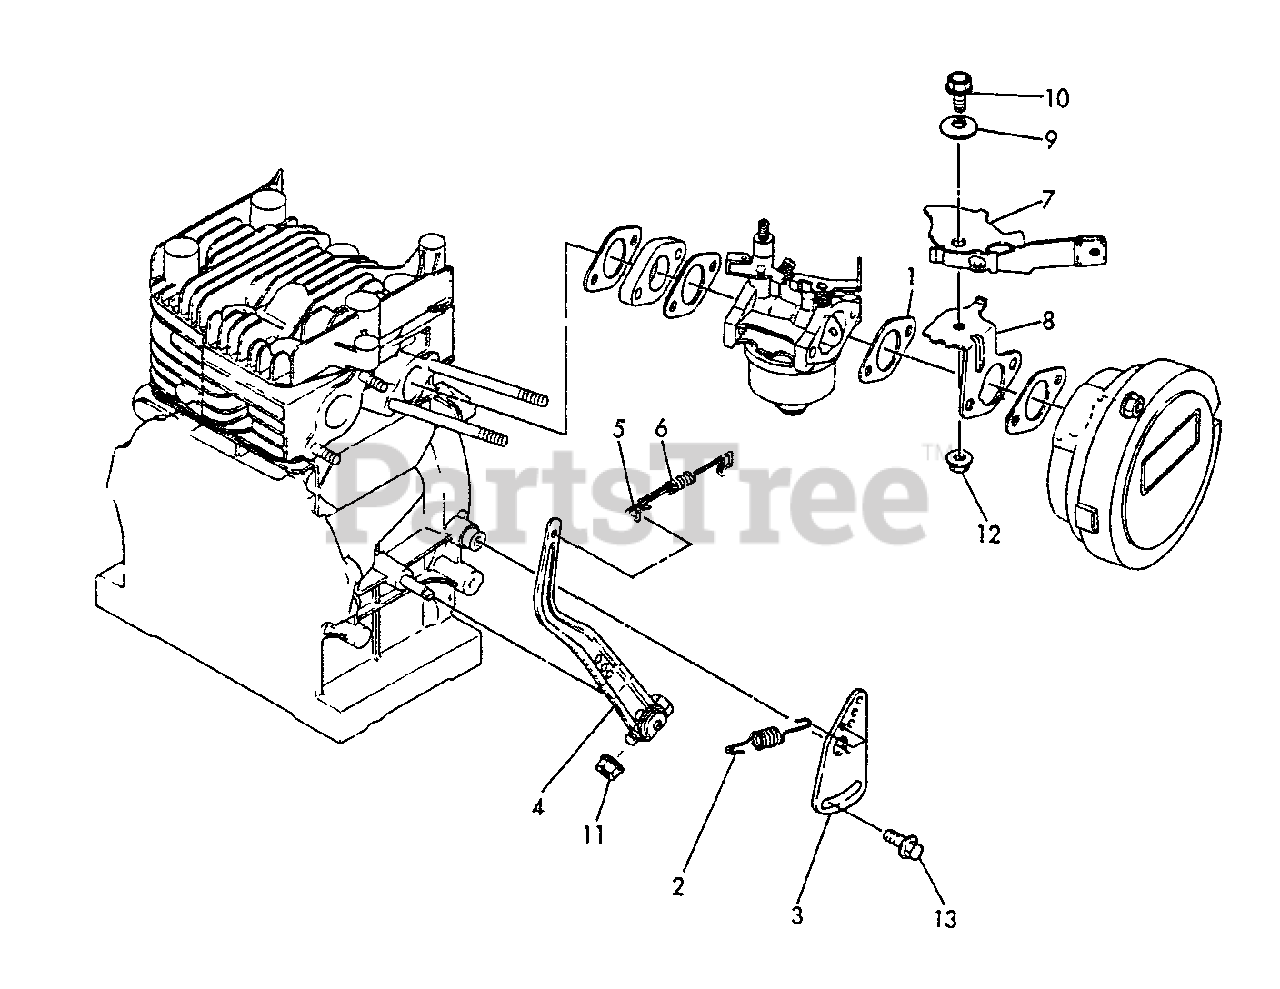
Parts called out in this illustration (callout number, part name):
1	GASKET, INTAKE
2	SPRING, REGULATOR
3	HANDLE, REGULATOR
4	LEVER, GOVERNOR
5	LINK, THROTTLE
6	SPRING
7	LEVEL ASSY
8	BRACKET
9	COLLAR
10	BOLT - 6X12 -- PLATED
11	NUT - 6 -- FLANGE
12	NUT - 8
13	BOLT - 6X8 -- PLATED
